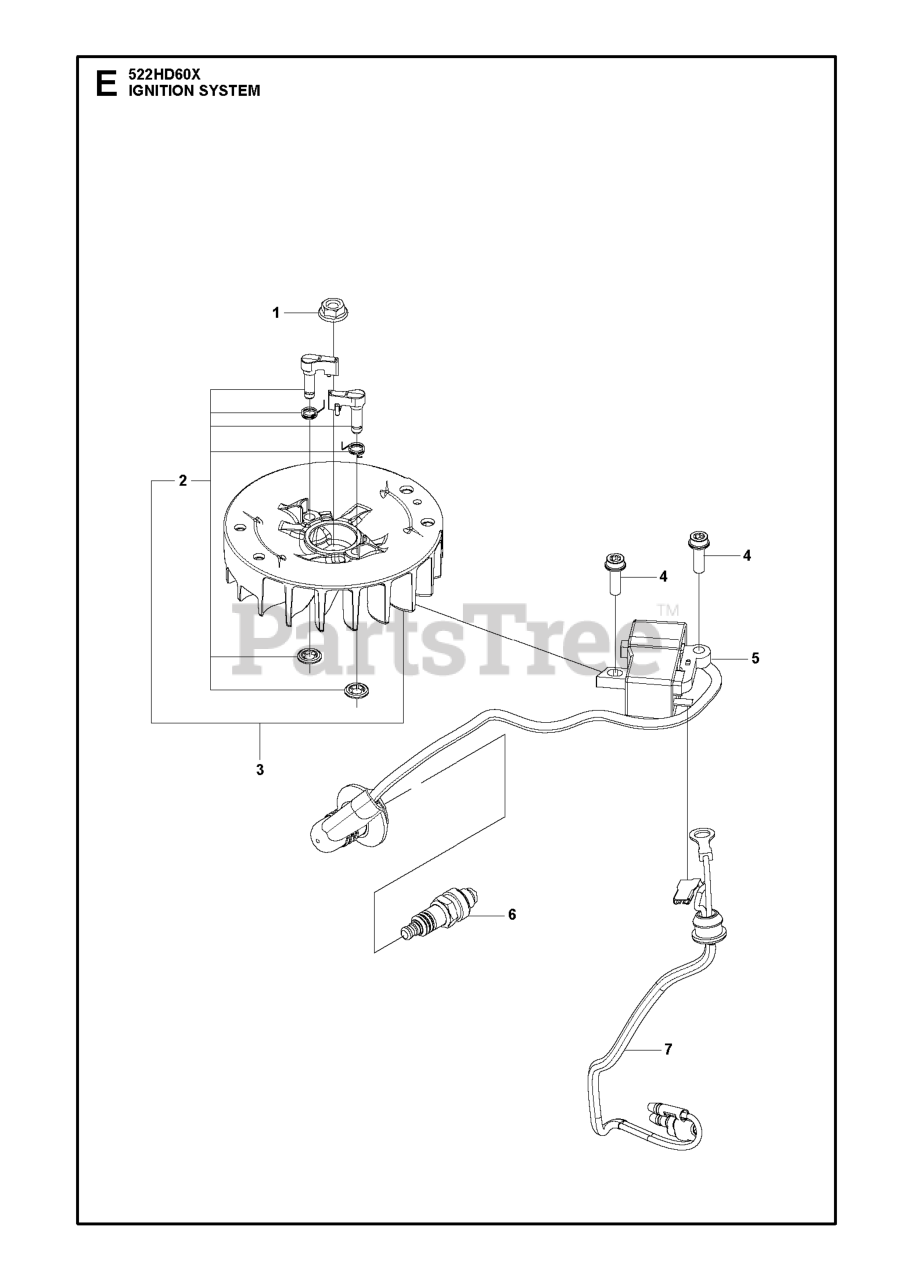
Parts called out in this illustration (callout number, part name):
1	FLANGE NUT
5	IGNITION MODULE A051
6	SPARK PLUG RESISTOR NGK CMR6A
7	SHORT CIRCUIT CABLE ENGINE A05
